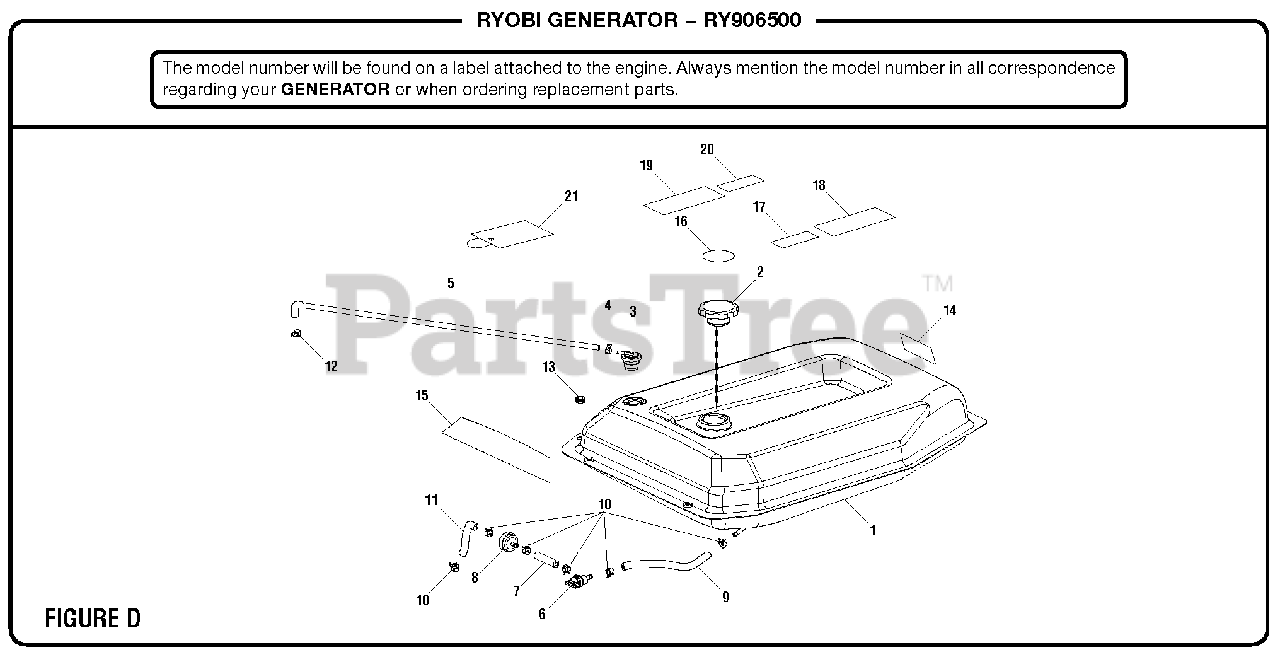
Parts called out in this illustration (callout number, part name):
1	Fuel Tank
3	Vapor Vent
4	Hose Clamp (10.3 mm)
5	Vapor Hose
6	Fuel Shut Off Valve
7	Fuel Hose (55 mm)
8	Fuel Filter
9	Fuel Hose (175 mm)
10	Hose Clamp (1/2 in.)
11	Fuel Hose (185 mm)
12	Hose Clamp (3/8 in.)
14	Combustion Label
15	Logo Label
16	Fuel Stabilizer Label (Eng.)
17	Fuel Stabilizer Label (Fr./Sp.)
18	CPSC Label
19	Warning Label
20	E85 Label
21	Danger Hang Tag
